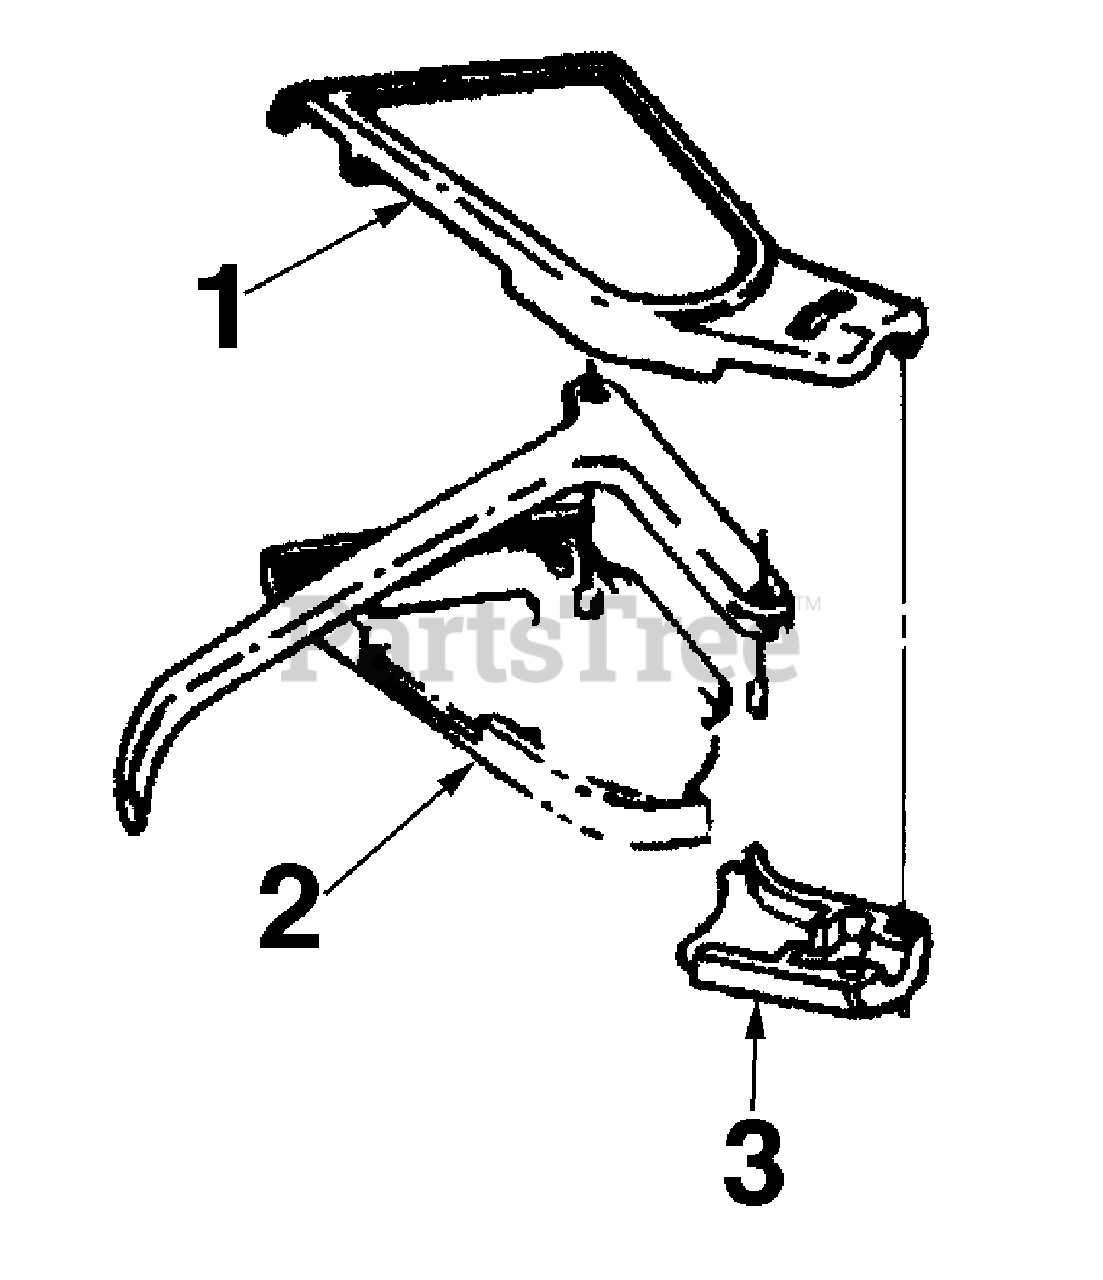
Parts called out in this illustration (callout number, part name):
1	Upper Control Cover
2	Lower Control Cover
3	Mounting Cap
